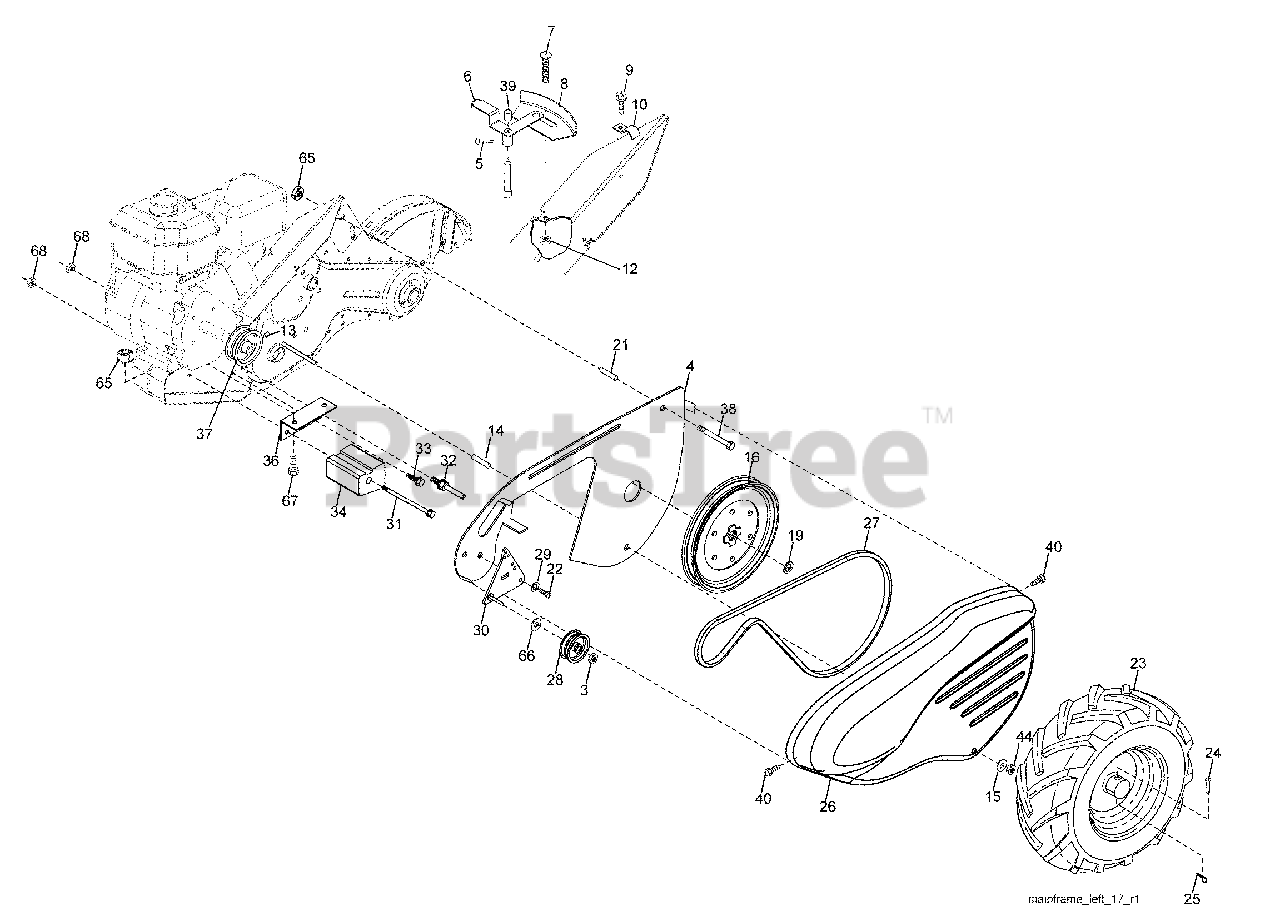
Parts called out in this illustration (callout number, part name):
3	Nut, Hex 3/8-16
4	Shield, Inner Belt Guard RT
5	Pin Spirol Flared
6	Lever, Shift
7	Bolt, Carriage 1/4-20 x 1/2 Gr. 5
8	Plate, Shift Indicator
9	Screw, Hex, Washer Head, Slotted #10-24 x ½
12	Nut, Keps Hex 1/4-20 unc
13	Screw, Set, Hex 5/16-18 x 3/8
14	Spacer, Split 0.327 x 0.42 x 2.09
15	Washer 11/32 x 11/16 x 16 Ga.
16	Sheave, Transmission
19	Retainer, Ring
21	Spacer, Split
22	Bolt, Fin Hex 5/16-24 unf x 1/2
24	Rivet, Drilled
25	Clip, Hairpin
26	Guard, Belt
27	Belt, V
28	Pulley, Idler
29	Ring, Klip
30	Bracket, Idler
31	Bolt, Hex 5/16-16 x 12
32	Shaft, Idler Arm
33	Bolt, Hex 3/8-16 x 1
34	Counterweight, L. H.
36	Bracket, Reinforcement, L. H.
37	Sheave, Engine
38	Bolt, Fin Hex 5/16-18 unc x 2-3/4
39	Cap, Plunger Blk
40	Screw Hex Wsh Slt #10-24 x 1/2
44	Nut Lock Hex w/Ins 5/16-18 unc PL
65	Nut Lock Hex Flange
66	Washer 13/32 x 13/16 x 12 Ga.
67	Bolt, Hex 5/16-18 x 1-3/4
68	Nut Keps Hex 3/8-16 unc
